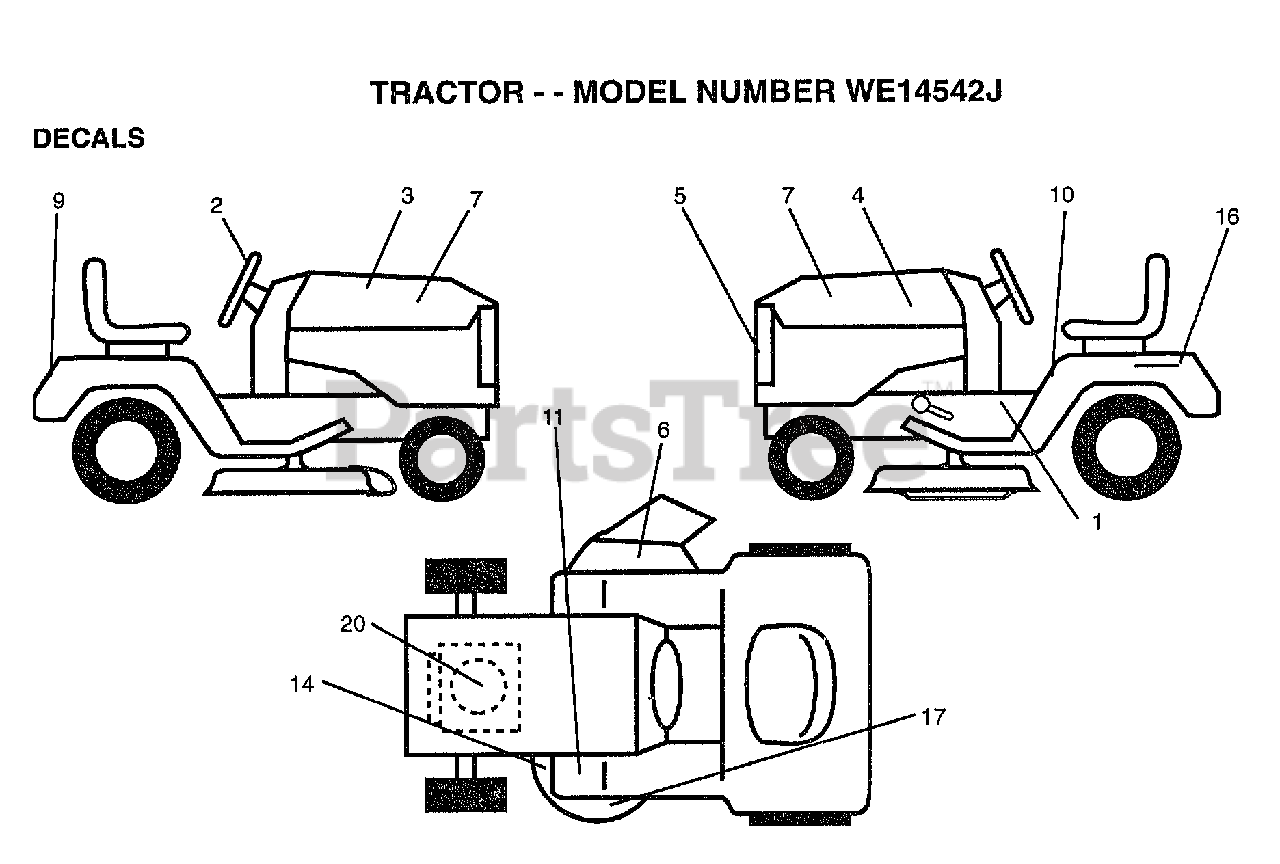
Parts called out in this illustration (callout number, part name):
1	"DECAL.OPER,SDL"
2	DECAL, INS STRG WH
3	DECAL.HOOD.RH.
4	DECAL.HOOD.LH
5	DECAL, GRILLE LENS
6	"DECAL, WARNING"
7	DECAL PANEL SIDE
9	DECAL.FENDER.LOGO
10	DECAL.CAUT.ENG/FR
11	DECAL T
14	"DECAL-SCHEM,BELT"
16	DECAL.BATRY.3-3908
17	DECAL, DECK GRASSEATER
20	DECAL.ENGINE
